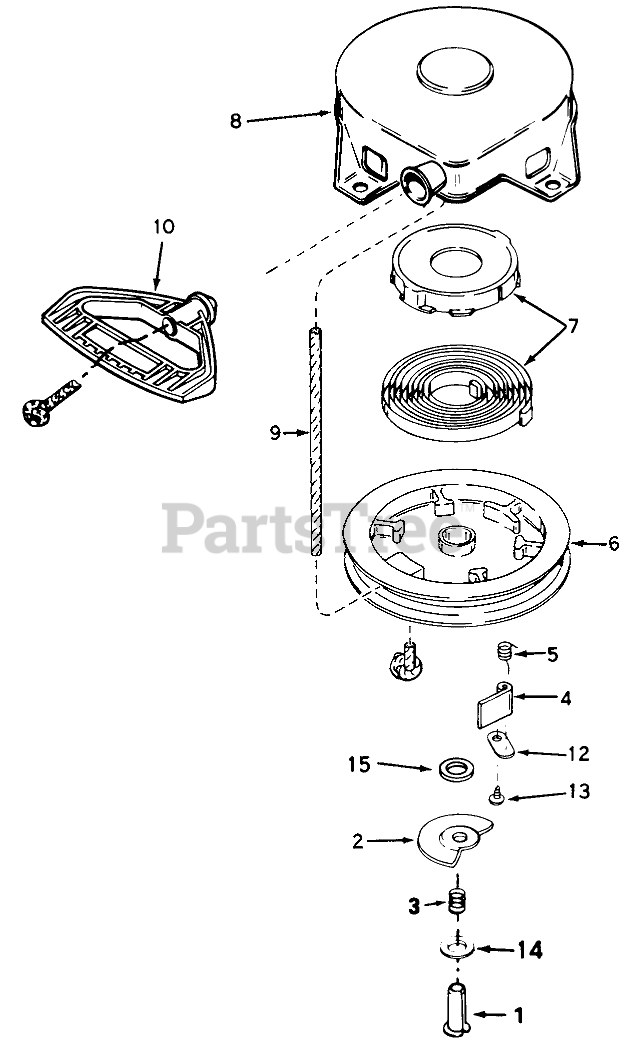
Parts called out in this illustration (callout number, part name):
1	Pin, Spring (Incl. Ref. #15)
3	Brake Spring
4	Dog-Starter
5	Spring-Dog
7	Spring & Keeper Assy
8	Housing-Starter
9	Rope-Starter
10	Handle-Starter, Mitten Grip
12	Retainer-Dog
